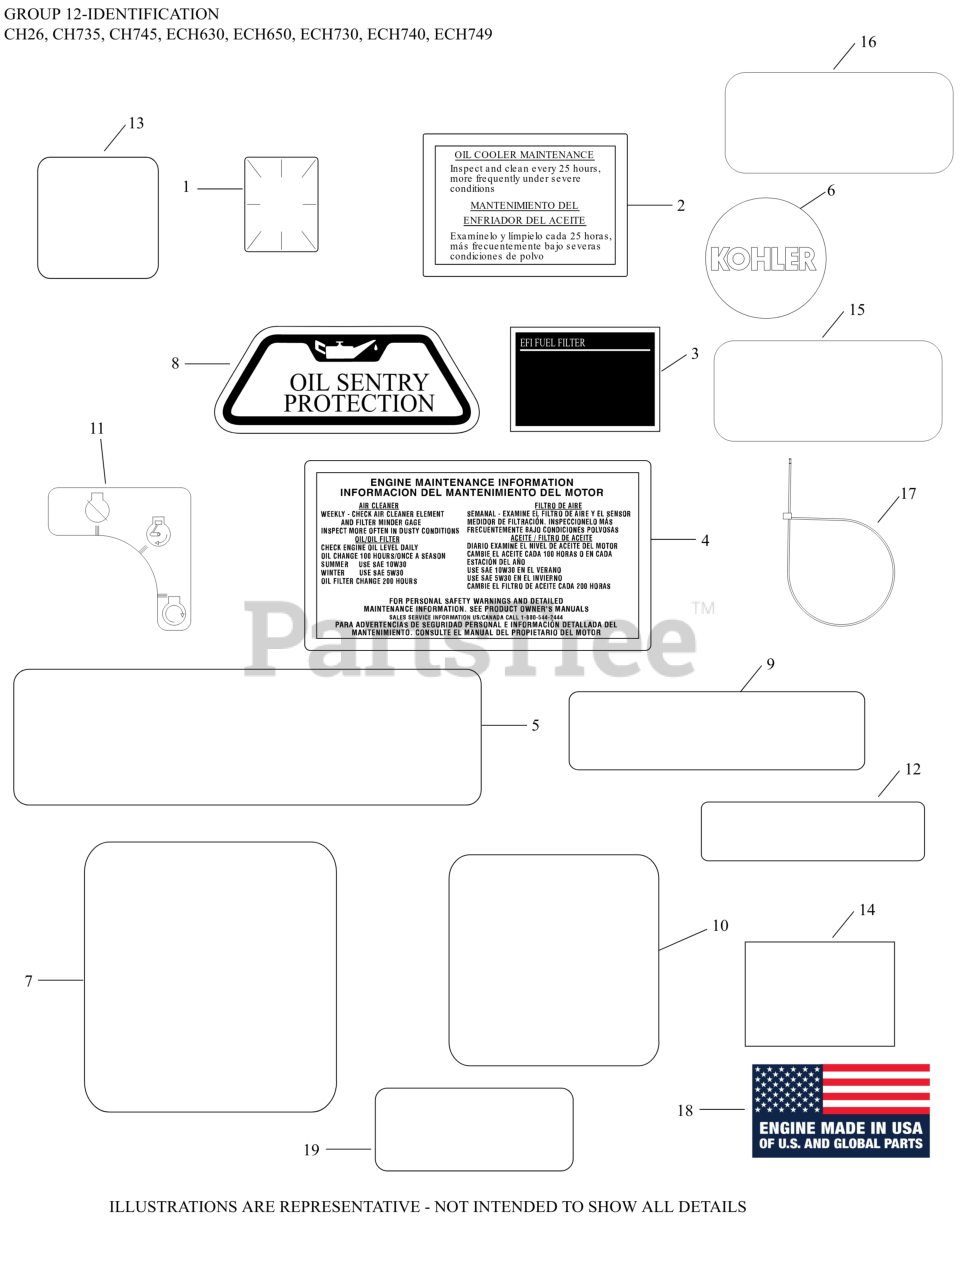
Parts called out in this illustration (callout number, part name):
1	LABEL, CLEAR LAMINATION
3	LABEL, EFI FUEL FILTER
10	DECAL, HDAC 26.5 HP/747cc/ECV-ECH749
